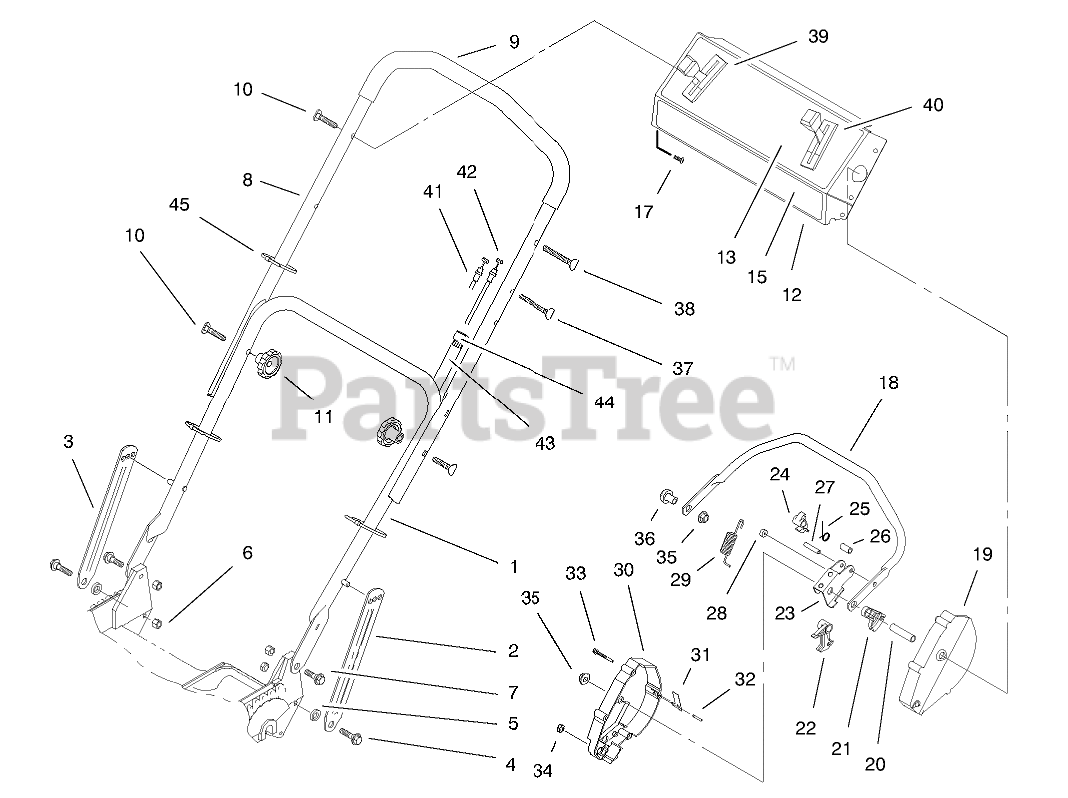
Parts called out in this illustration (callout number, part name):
1	ASM-Handle
2	Latch-Handle
3	Latch-Handle
4	SCREW-SHOULDER
5	SPACER
6	NUT-LOCK, NI
7	SCREW-SHOULDER
8	Handle-Upper
9	Grip-Foam
10	SCREW-HANDLE
12	Panel-Control (Incl. Ref. #13)
13	DECAL - INSRTUCTION
15	DECAL - CONSOLE
17	SCREW-TAP
18	Bar-Control
19	HOUSING-CONTROL, LH
20	TUBING-SPACER
21	LEVER-TRACTION
22	ROCKER
23	LEVER-CABLE
24	HOOK-CONTROL
25	SPRING-TORSION
26	SPACER
27	PIN-ROLL, SLOTTED
28	WASHER-NYLON
29	SPRING-DETENT
30	Housing-Control
31	SPRING-LEAF
32	PIN-INSERT
33	SCREW-HWHTF
34	NUT-LOCK NI
35	NUT-LOCK NI
36	SPACER-SUPPORT
37	SCREW-HANDLE
38	OBS MATERIAL EXCEPT FOR SERVICE
39	CONTROL-SPEED, GROUND
40	THROTTLE CONTROL
41	CLUTCH CABLE
42	TRACTION CABLE
43	CONTROL CABLE COVER
44	FITTING-RING
45	TIE-CABLE
